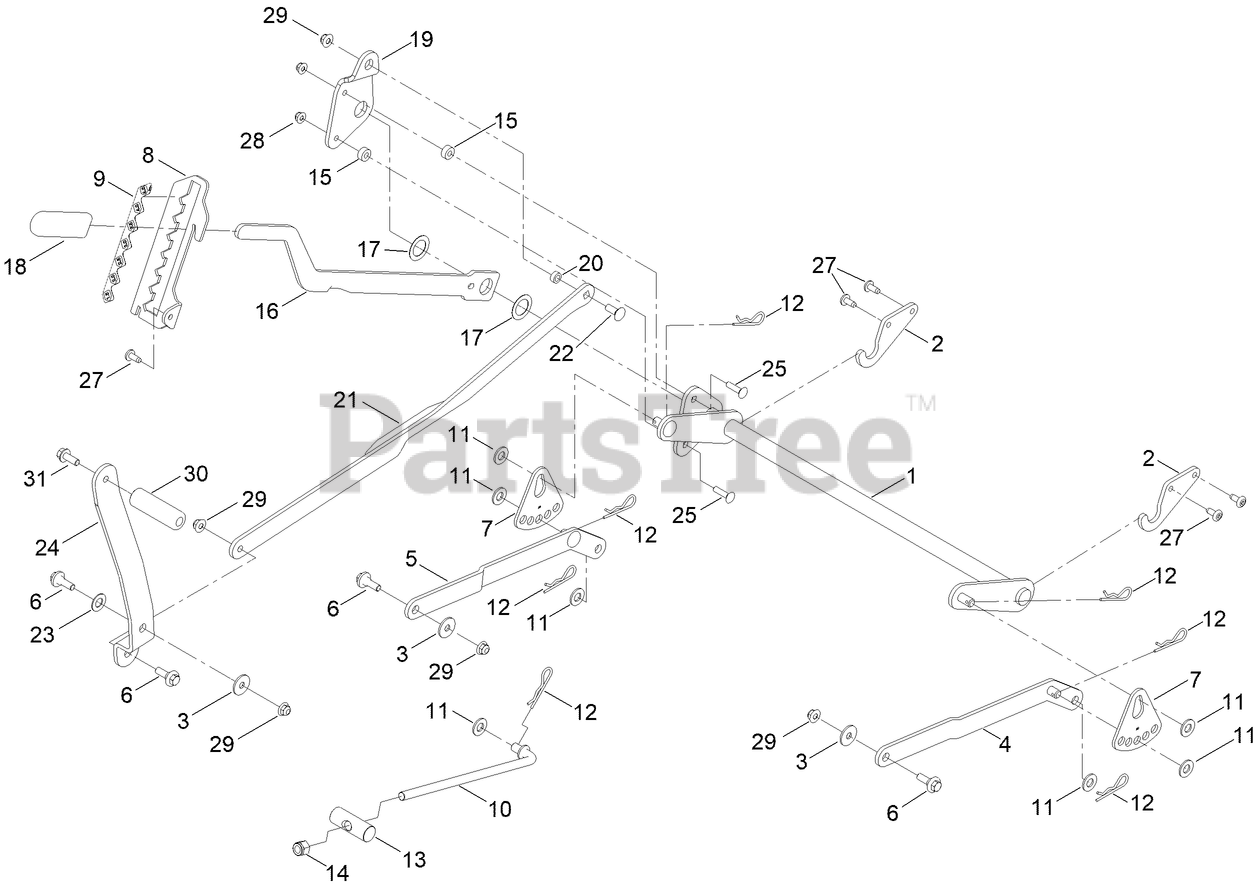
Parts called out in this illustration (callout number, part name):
1	DECK LIFT ASM
2	BRACKET-PIVOT, DECKLIFT
3	WASHER-HARDENED, CZ
4	LH ARM ASM
5	RH ARM ASM
6	SCREW-SHOULDER
7	PLATE-HOC ADJUSTMENT
8	BRACKET-HOC
9	DECAL-HOC
10	ROD-MOUNT, DECK
11	WASHER-FLAT
12	PIN-HAIR
13	PIN-PIVOT
14	NUT-HEX
15	SPACER
16	LEVER-LIFT
17	WASHER-THRUST
18	GRIP-LEVER
19	PLATE-FOOTLIFT
20	SPACER
21	LINK ASM
23	WASHER-NYLON
24	PEDAL-LIFT
25	BOLT-CARRIAGE
28	NUT-HF
29	NUT-HF, NI
30	PEDAL-FOOT LIFT
31	SCREW-HHF
